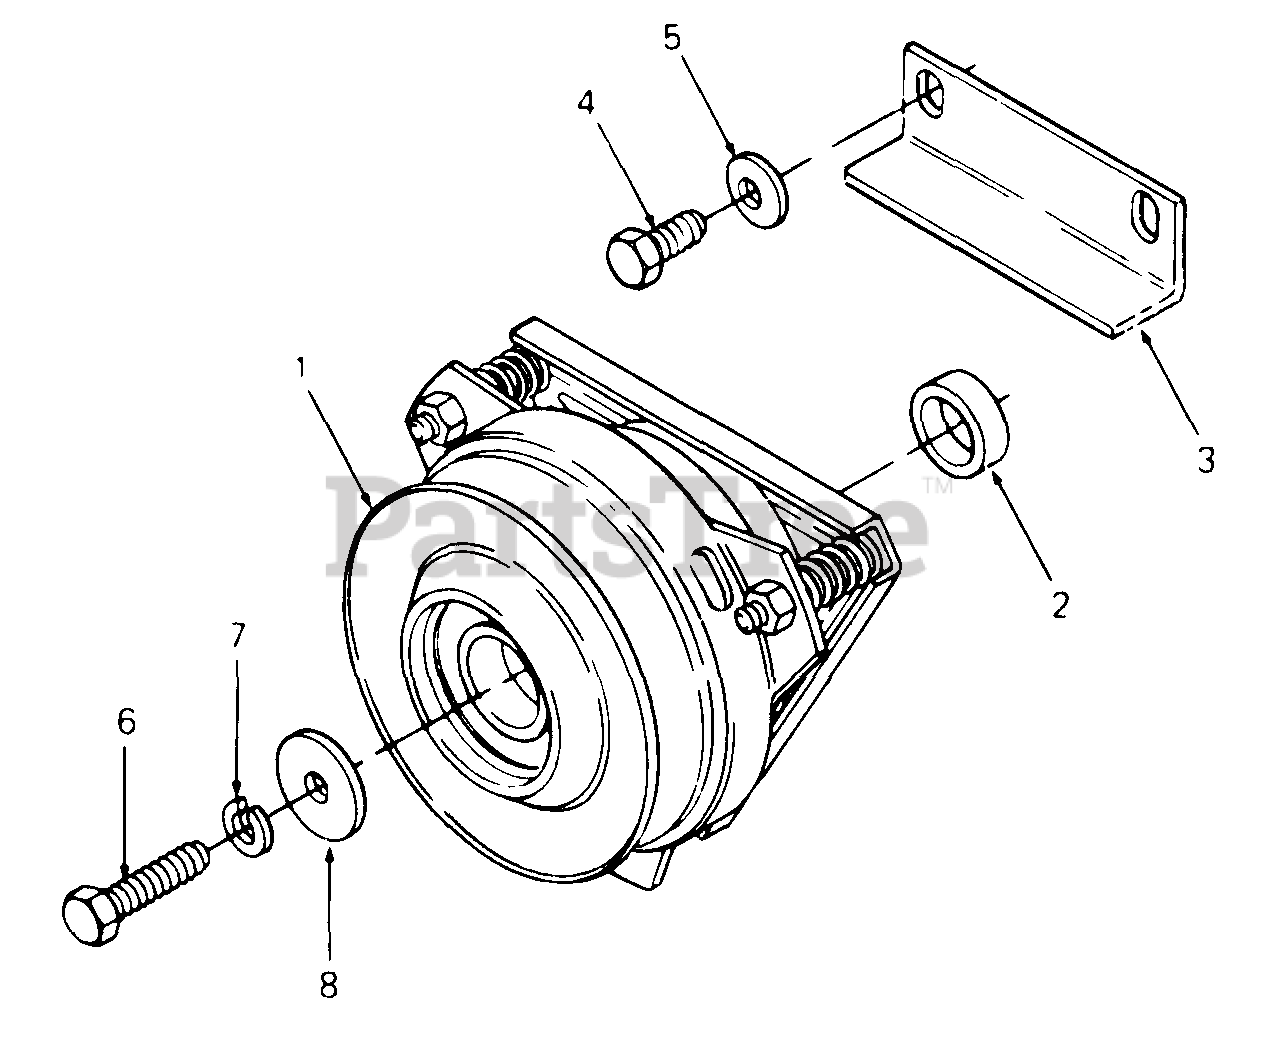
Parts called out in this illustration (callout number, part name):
1	Clutch, PTO
2	Spacer
5	Washer, Bell, .45 X 1.0 X .062 Thk
6	Screw, Hex Cap, 3/8-24 X 2.00 Lg GR5
7	Washer, Lock, 3/8
8	Washer, Flat, .445 X 1.5 X .172 Thk
